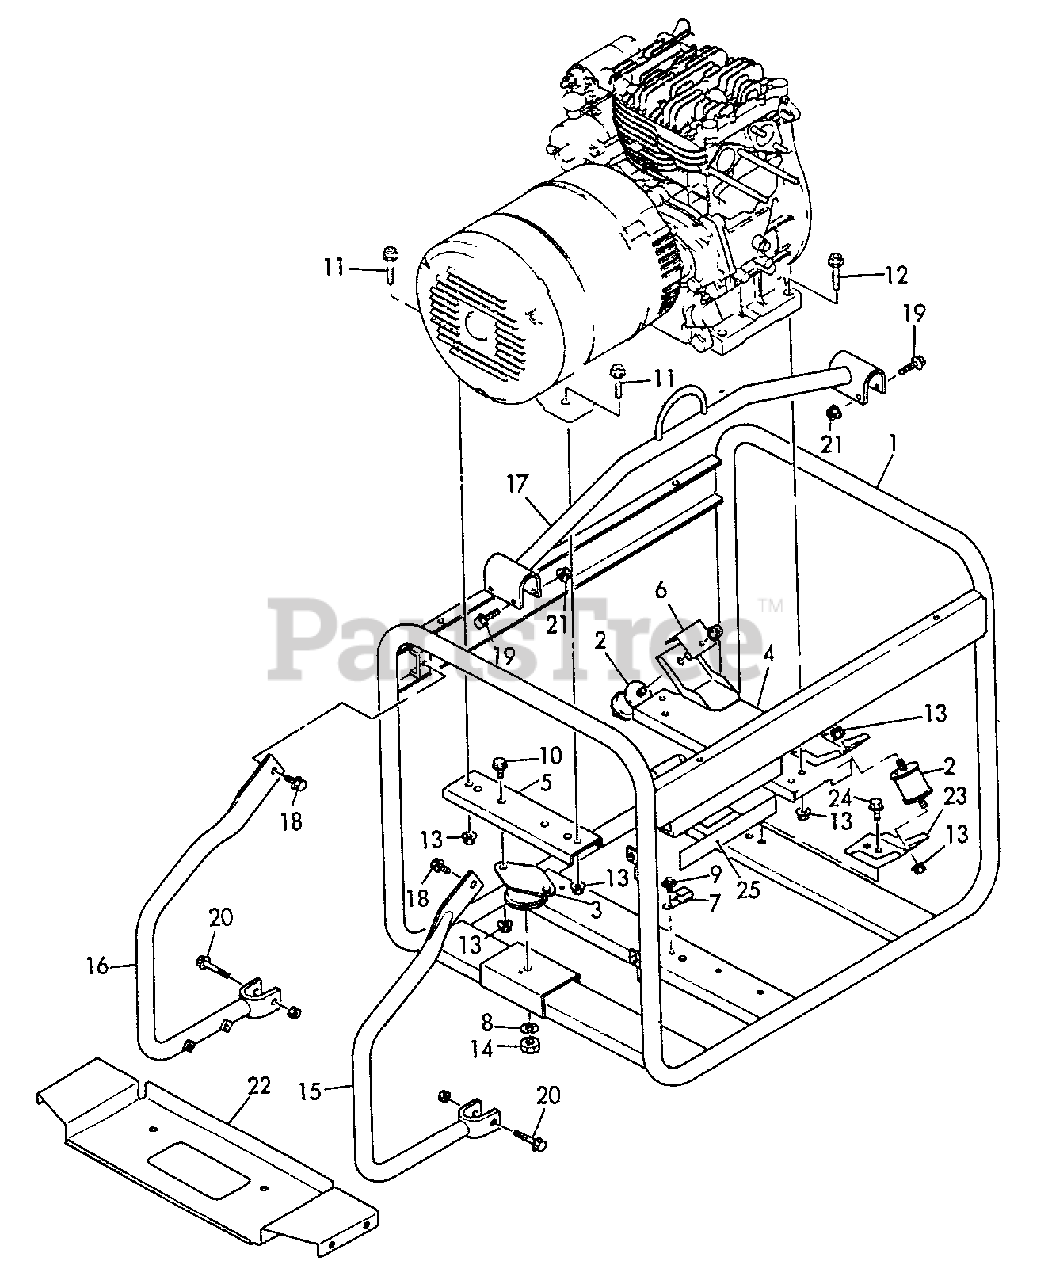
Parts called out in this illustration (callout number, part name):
1	FRAME
2	DAMPER, FRONT
3	DAMPER, REAR
4	STAY, DAMPER
5	STAY, REAR DAMPER
6	COVER, DAMPER
7	CLAMP
8	LOCKWASHER - 10
9	BOLT - 6X8 -- PLATED
10	BOLT - 8X20 -- PLATED
11	BOLT - 8X30 -- PLATED
12	BOLT - 8X38 -- PLATED
13	NUT - 8
14	NUT - 10
15	SIDE, FRAME -RIGHT
16	SIDE, FRAME - LEFT
18	BOLT - 6X12 -- PLATED
19	BOLT - 6X30
20	BOLT - 6X40
21	NUT - 6 -- FLANGE
22	BRACKET, BATTERY
23	DAMPER STAY, LOWER
24	BOLT - 8X16 -- PLATED
25	SHEET, FRAME
